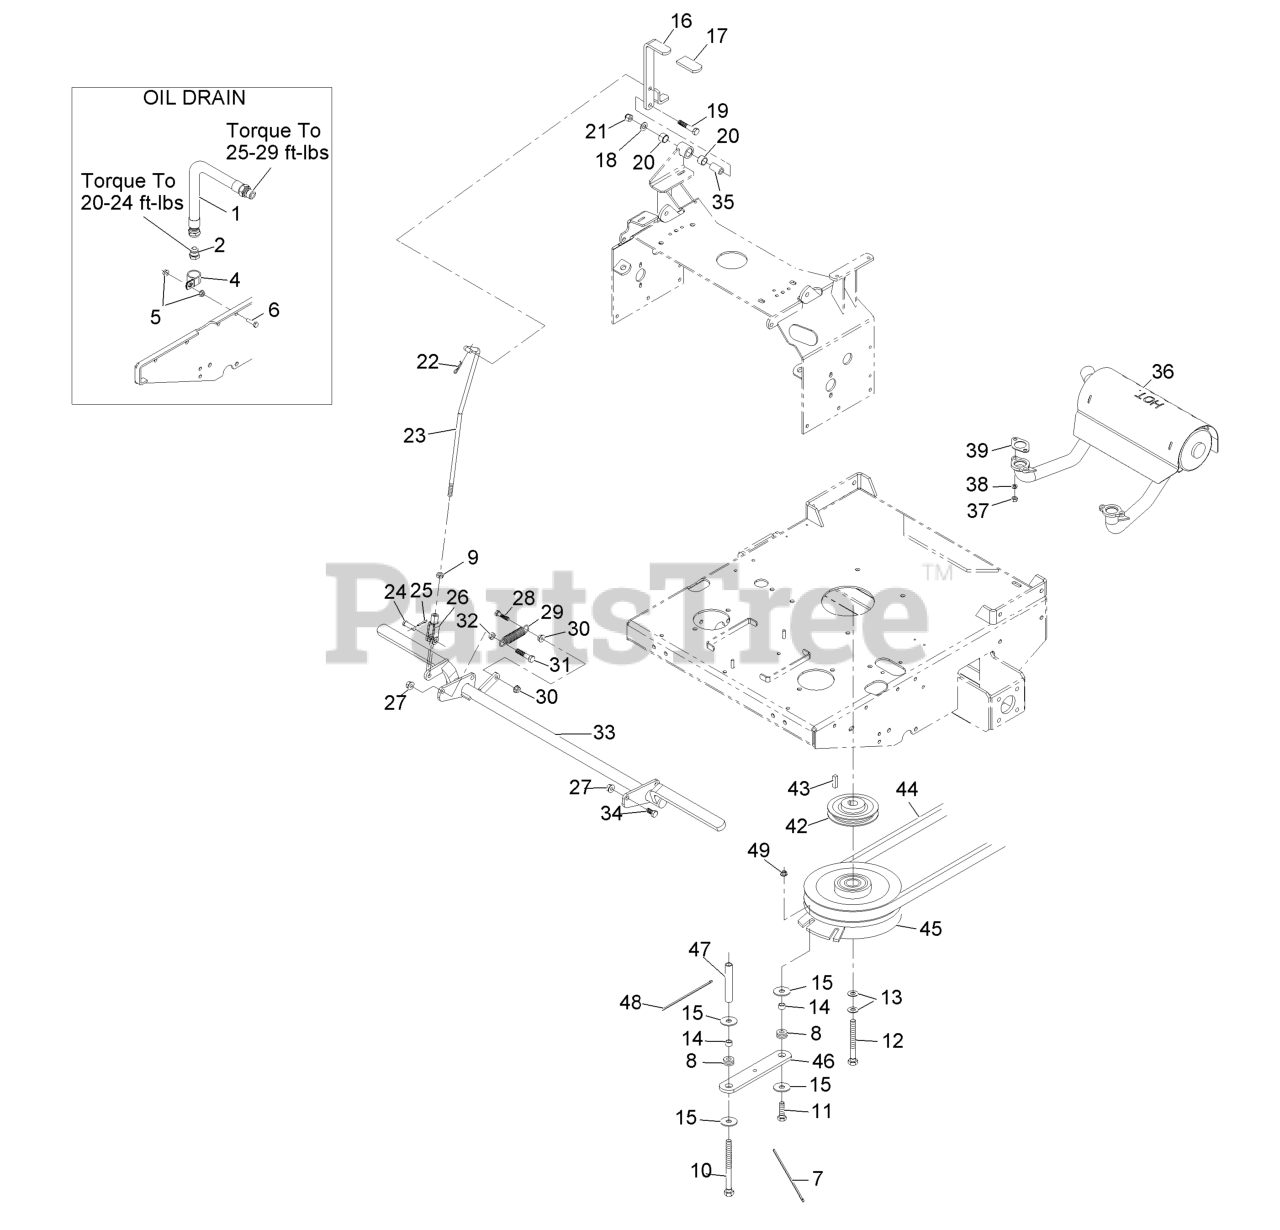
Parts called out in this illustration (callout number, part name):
4	CLIP-LOOM
6	SCREW-HH
7	TIE-PLASTIC
8	GROMMET
9	NUT-HJ
10	SCREW-HH
11	SCREW-HH
12	SCREW-HH
13	WASHER-SPRING
16	LEVER,PRK BRK W/DECALS
17	GRIP-LEVER
18	WASHER-FLAT
19	SCREW-HH
20	SLEEVE-BUSHING
21	NUT-LOCK, NI
22	PIN-COTTER
23	LINKAGE, PARK BRAKE
24	PIN-CLEVIS
25	PIN-COTTER
26	YOKE-LINKAGE, BRAKE
27	NUT-HHF, WHIZ
28	SCREW-HH, SPECIAL
29	SPRING-IDLER
31	SCREW-HH
32	NUT-JAM
34	SCREW-HH
35	BUSHING-PIVOT
36	MUFFLER,HORIZONTAL
38	WASHER-LOCK
39	GASKET-EXHAUST
42	PULLEY
44	BELT,B 83.65
44	BELT,DECK DRIVE
45	CLUTCH ASM
46	STRAP-CLUTCH, BRAKE
47	SPACER,SHIELD
48	TIE-CABLE
